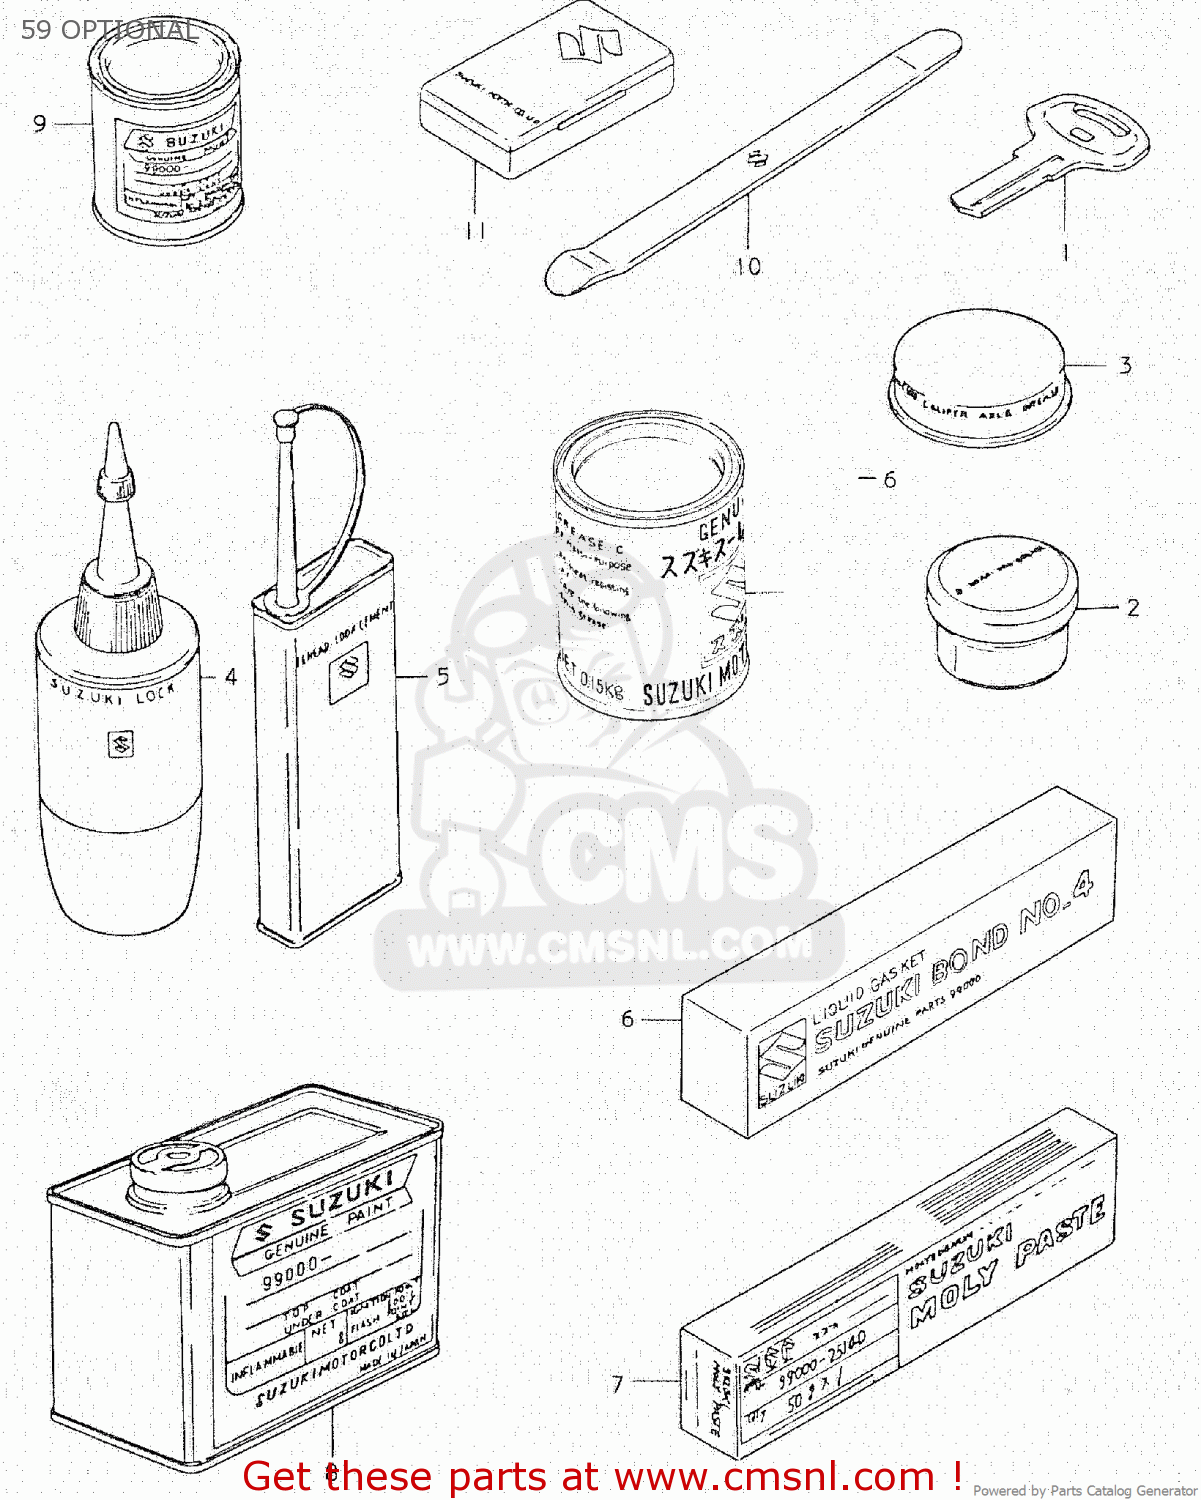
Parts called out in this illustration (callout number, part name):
1	KEY,BLANK
2	GREASE,SILICON 20G
3	GREASE,PBC FOR BRK PAD 20G
4	THREAD LOCK NO.1303B PURPL 50G
5	THREAD LOCK NO.1401 CLEAR 200G
6	BOND 1104
7	SUZUKI MOLY PASTE
8	PAINT (BLACK)
9	PAINT,BLACK
10	LEVER,TIRE
11	GASKET SET (NAS)
